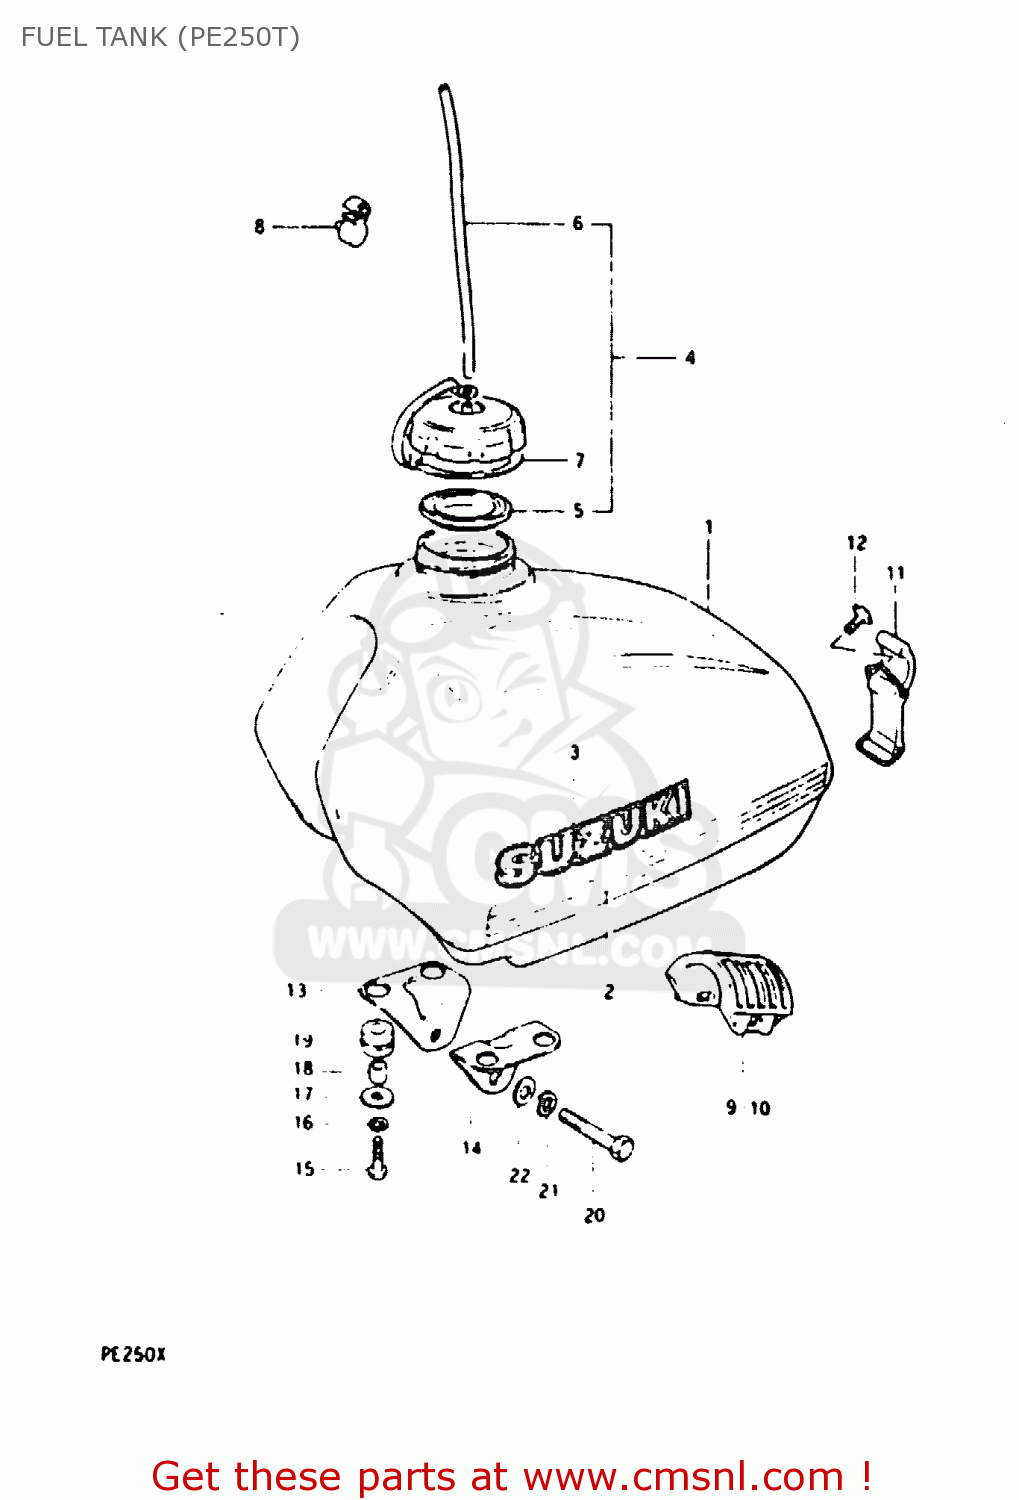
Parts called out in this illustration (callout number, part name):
1	TANK ASSEMBLY,FUEL
2	TAPE SET,FUEL TANK
3	EMBLEM
4	CAP,FUEL TANK
5	GASKET,FUEL TANK CAP (NAS)
6	HOSE
7	BAND,FUEL TANK CAP
8	CLAMP,BREATHER HOSE
9	CUSHION,FUEL TANK
10	CUSHION,FUEL TANK
11	BAND
12	SCREW(6X18)
13	BRACKET,FUEL TANK
14	BRACKET,FUEL TANK,LOWER
15	SCREW
16	LOCK WASHER
17	WASHER (6.5X24X1.6)
18	SPACER(6.8X12X11)
19	CUSHION
20	BOLT
21	LOCK WASHER
22	WASHER
